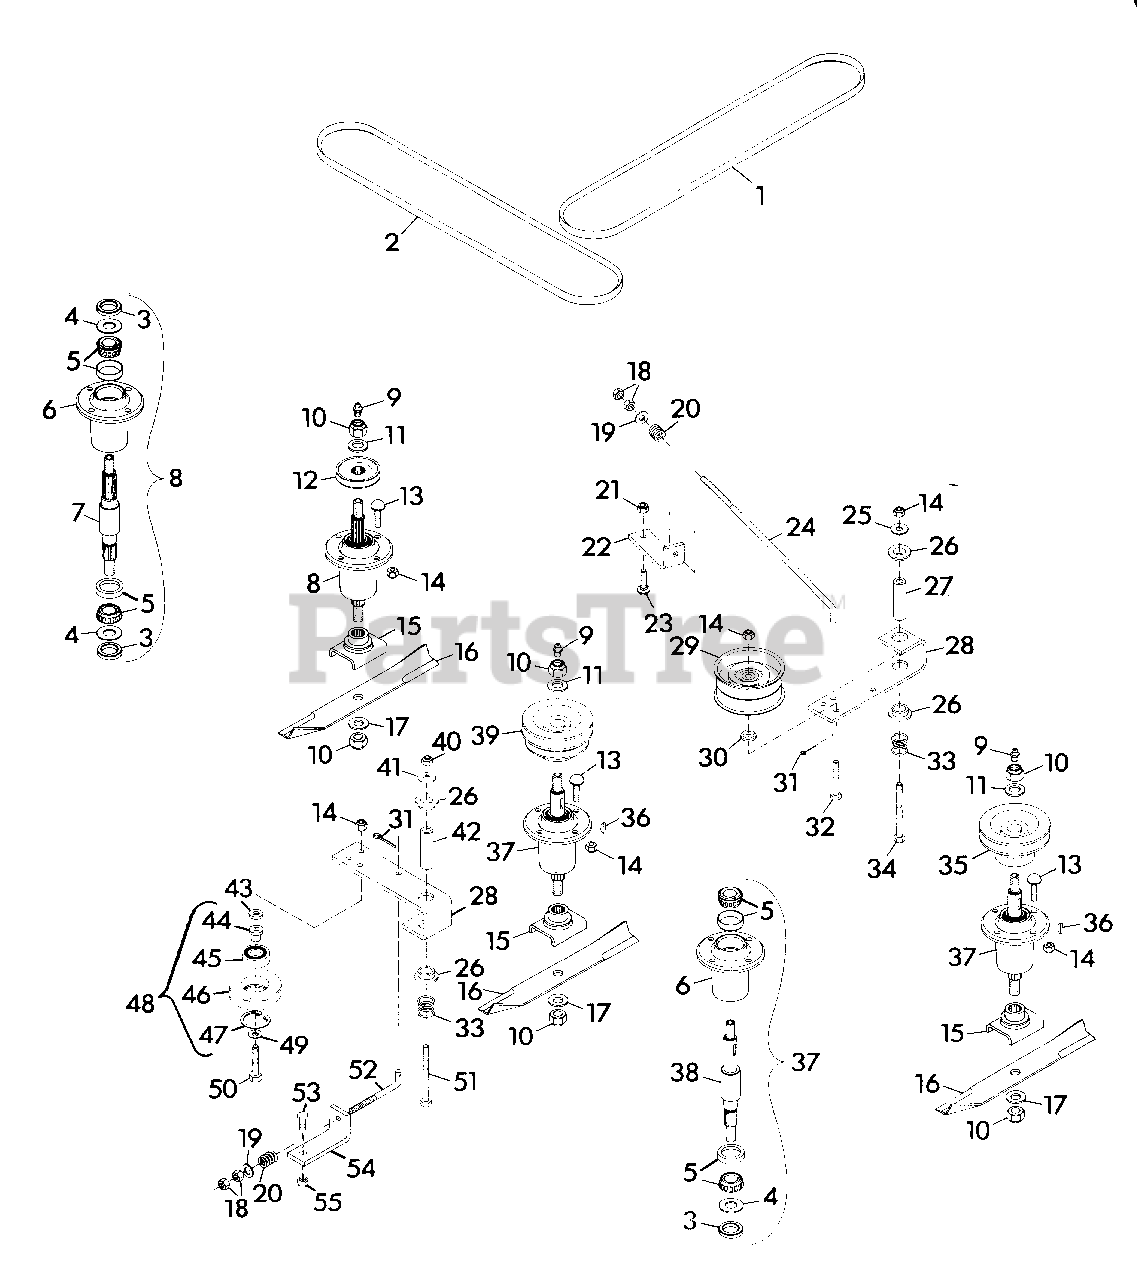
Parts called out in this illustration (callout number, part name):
1	BELT, PRO-40 MOWER
2	BELT, MOWER A44
3	SEAL, STEEL(IN 34605)
3	SEAL, STEEL(IN 21306)
4	WASHER, FLAT .975X1.970X.030(IN 34605)
4	WASHER, FLAT .975X1.970X.030(IN 21306)
5	ASSEMBLY, BEARING
6	HOUSING, BEARING
7	SHAFT, SPINDLE
8	ASSEMBLY, SPINDLE
9	FITTING, LUBE 1/8
10	NUT, LOCK 5/8-11
11	WASHER, FLAT .687X1.312X.122
12	SHEAVE, SPINDLE
13	BOLT 3/8-16X1.25 RD HD SQ NK
14	NUT, LOCK 3/8-16
15	WELDMENT, BLADE CRADLE
16	BLADE
17	WASHER, FLAT .656X1.312X.095
18	NUT, HEX 3/8-16
19	WASHER, FLAT .406X.812X.065
20	SPRING, COMP. 1X.78
21	NUT, LOCK 5/16-18
22	BRACKET, BELT TENSIONER
23	BOLT, CARRIAGE 5/16-18X1.00
24	ROD, IDLER
25	WASHER, FLAT .438X1.000X.083
26	BUSHING, NYLON .76X1X.6 FLG.
27	SPACER
28	ARM, IDLER PIVOT
29	PULLEY, IDLER
30	BUSHING
31	PIN, COTTER .09X.75
32	BOLT, HEX 3/8-16X2.25
33	SPRING, COMP. 1X.80X36 LB/N
34	BOLT, HEX 3/8-16X3.25
35	SHEAVE, SPINDLE
36	KEY, WOODRUFF .250X1 HARD
37	ASSEMBLY, SPINDLE
38	SHAFT, SPINDLE
39	SHEAVE, SPINDLE
40	NUT, LOCK 1/2-13
41	WASHER, FLAT .531X1.250X.100
42	SPACER
43	SPACER, IDLER .406X.750X.188
44	BUSHING, IDLER SHEAVE
45	BEARING, BALL
46	SHEAVE, IDLER
47	RING, RETAINING
48	ASSEMBLY, IDLER SHEAVE
49	WASHER, FLAT .375X1.125X.065
50	BOLT, HEX 3/8-16X2.00
51	BOLT, HEX 1/2-13X3.50
52	ROD, IDLER
53	BOLT, HEX 1/2-13X1.25
54	BRACKET, BELT TENSIONER
55	NUT, LOCK 1/2-13
